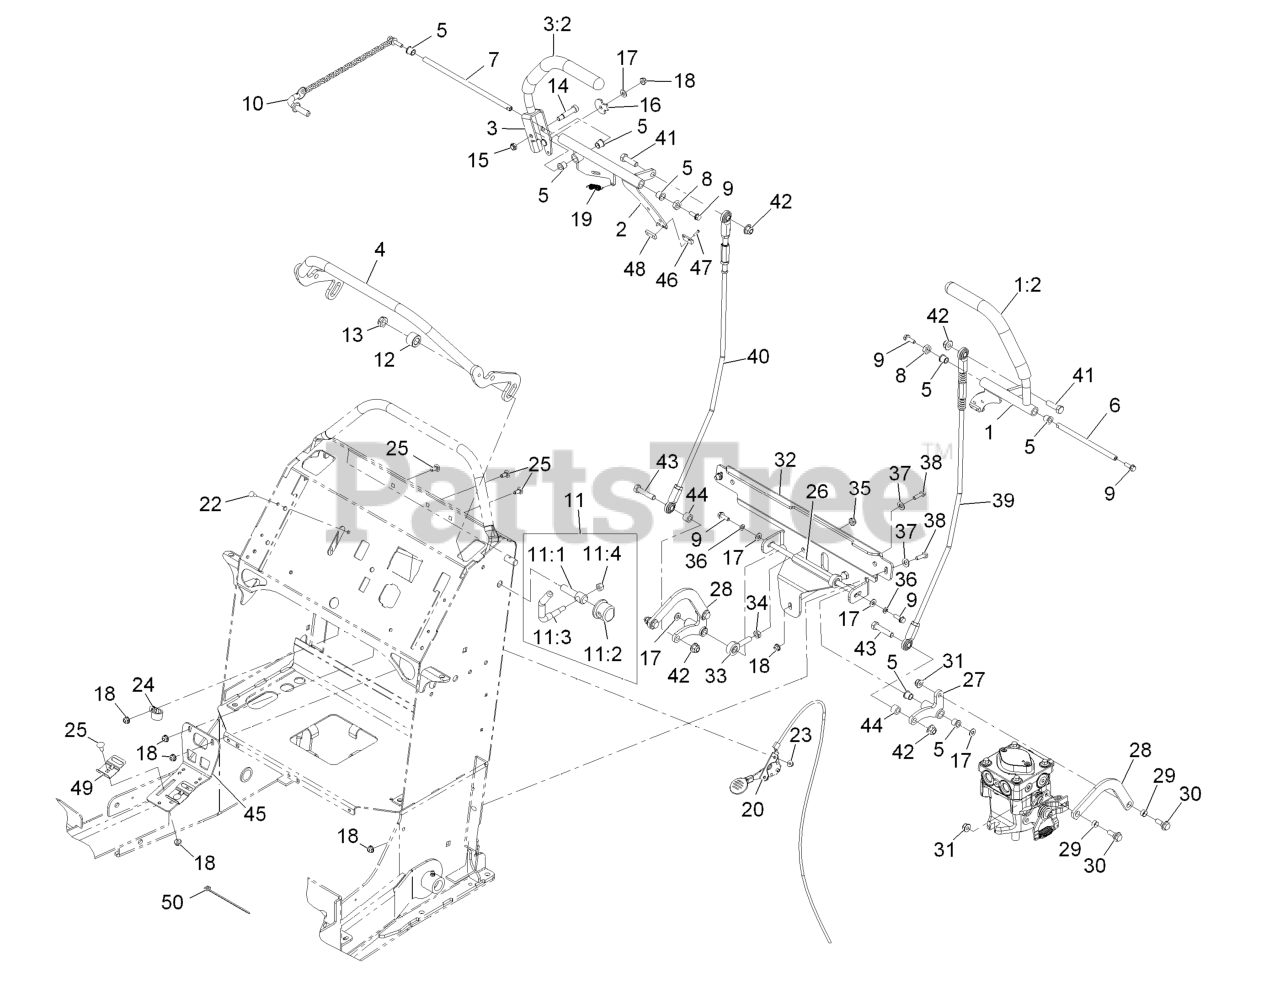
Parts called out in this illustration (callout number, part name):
1	LEVER ASM, LH
1:2	GRIP-HANDLE, CONTROL
2	MOTION CONTROL ASM-RH
3	LEVER ASM, RH
3:2	GRIP-HANDLE, CONTROL
5	BEARING
6	SHAFT-PIVOT, MOTION CONTROL
7	SHAFT-PIVOT, MOTION CONTROL
8	SPACER-SHAFT, DRIVE LEVER
9	SCREW-HHF
10	HOC PIN ASM
11	LEVER ASM
11:1	SCREW-LOCK
11:2	CAP-LOCK
11:4	NUT-LOCK, NI
12	SPACER-CLAMP
13	NUT-HEX
14	SCREW-HSH
15	NUT-LOCK, NI
16	CAM-LEVER
17	WASHER-FLAT
19	SPRING-EXTENSION
20	CONTROL-THROTTLE
22	BOLT-CARR
23	NUT-LOCK, FLANGE
24	CLAMP-CABLE
25	SCREW-CARR
26	SHAFT-BELLCRANK PIVOT
27	BELLCRANK-CONTROL, MOTION
28	LINK-BELLCRANK, PUMP
29	BUSHING-SLEEVE
30	SCREW-SHOULDER
31	NUT-HF, NI
32	BRACKET-BELLCRANK
33	BALLJOINT
34	NUT-HJ
35	NUT-HEX
36	SCREW-HH
37	WASHER-PLAIN
38	SCREW-HH
39	LINKAGE-TRACKING CONTROL,LH
40	LINKAGE-TRACKING CONTROL,RH
41	SCREW-HH
42	NUT-HF, NI
43	SCREW-HH
44	SPACER-WHEEL
45	BRACKET, REED SWITCH
46	ACTUATOR-SWITCH, REED
47	SCREW-HH
48	PLATE-TAPPED
49	CLAMP, REED SWITCH
50	TIE-CABLE
